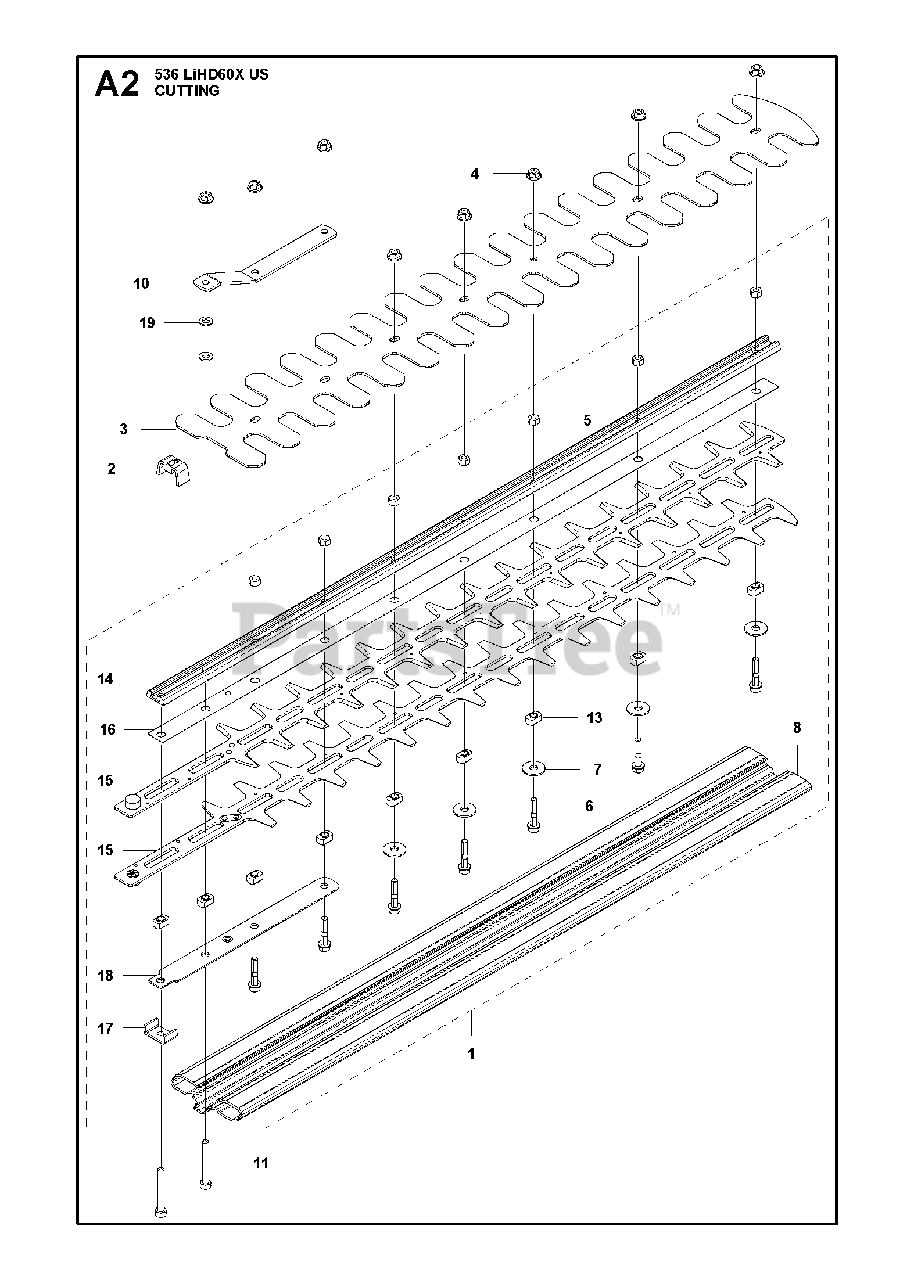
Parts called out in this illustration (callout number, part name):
1	CUTTING DECK LIHD HD60 US INCR
4	HEXAGON NUT FLANGE M5 8 ZN/FE
5	HEXAGON NUT ISO 4032-M5-10
6	SCREW IHSCFM M5X25 10.9 ZN/FE
7	WASHER 6,4X18X1,5
8	TRANSPORT GUARD CUTTING DECK H
10	SUPPORT CUTTING DECK
11	SCREW IHSCT EN ISO 4762 / DIN
13	SPACER HEDGE TRIMMER
14	BAR CUTTING DECK LIHD60
15	BLADE ASSY HD60 SLOTS INCR.
16	WEAR PLATE HD60
17	BRACKET
18	BAR
